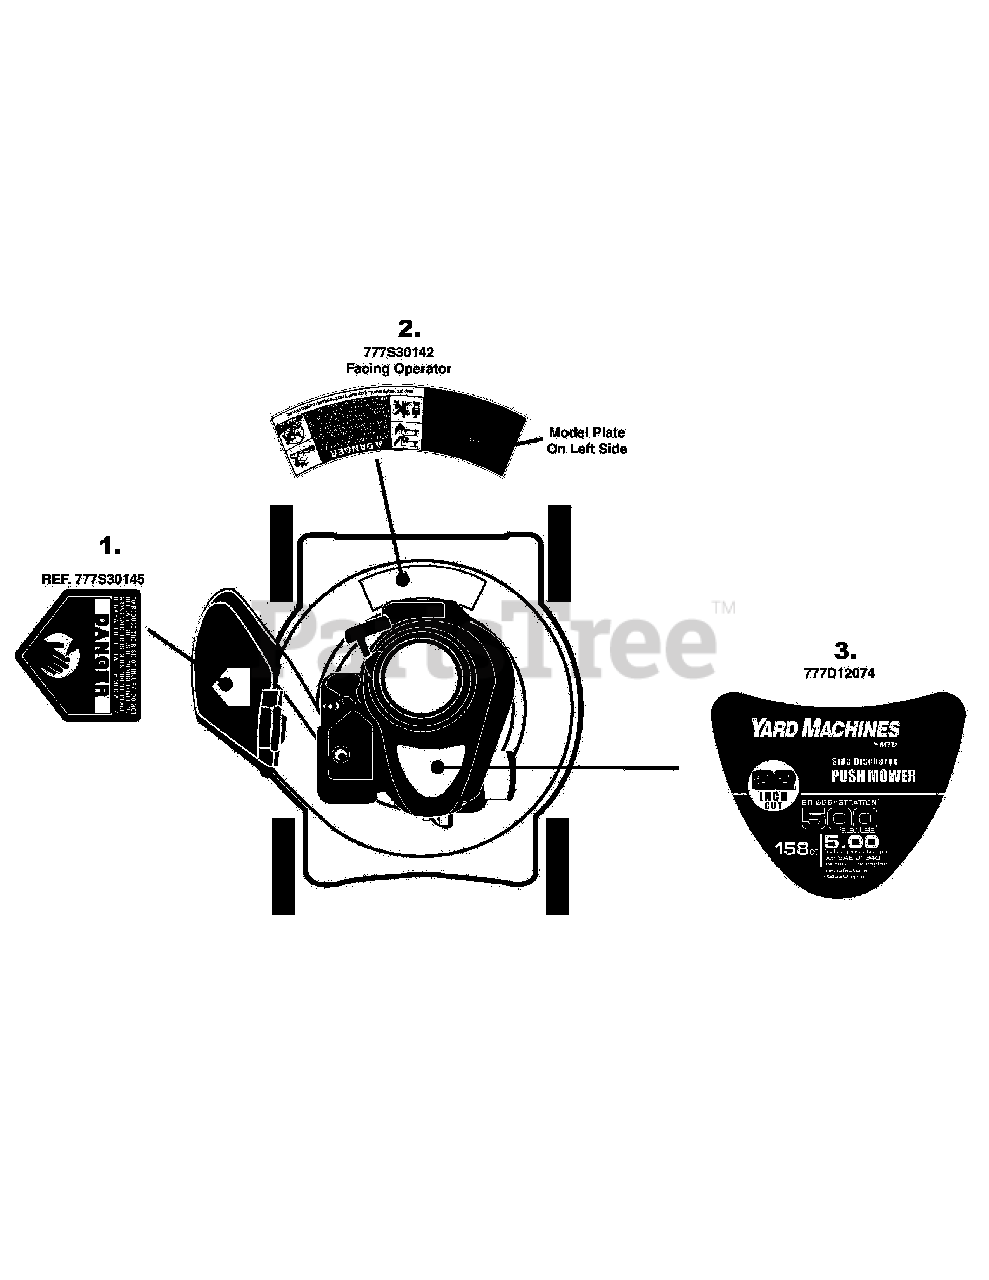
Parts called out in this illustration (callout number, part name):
1	LABEL
2	LABEL-DANGER CURVE
3	LABEL-MOWER SHROUD YARD MACHINES
